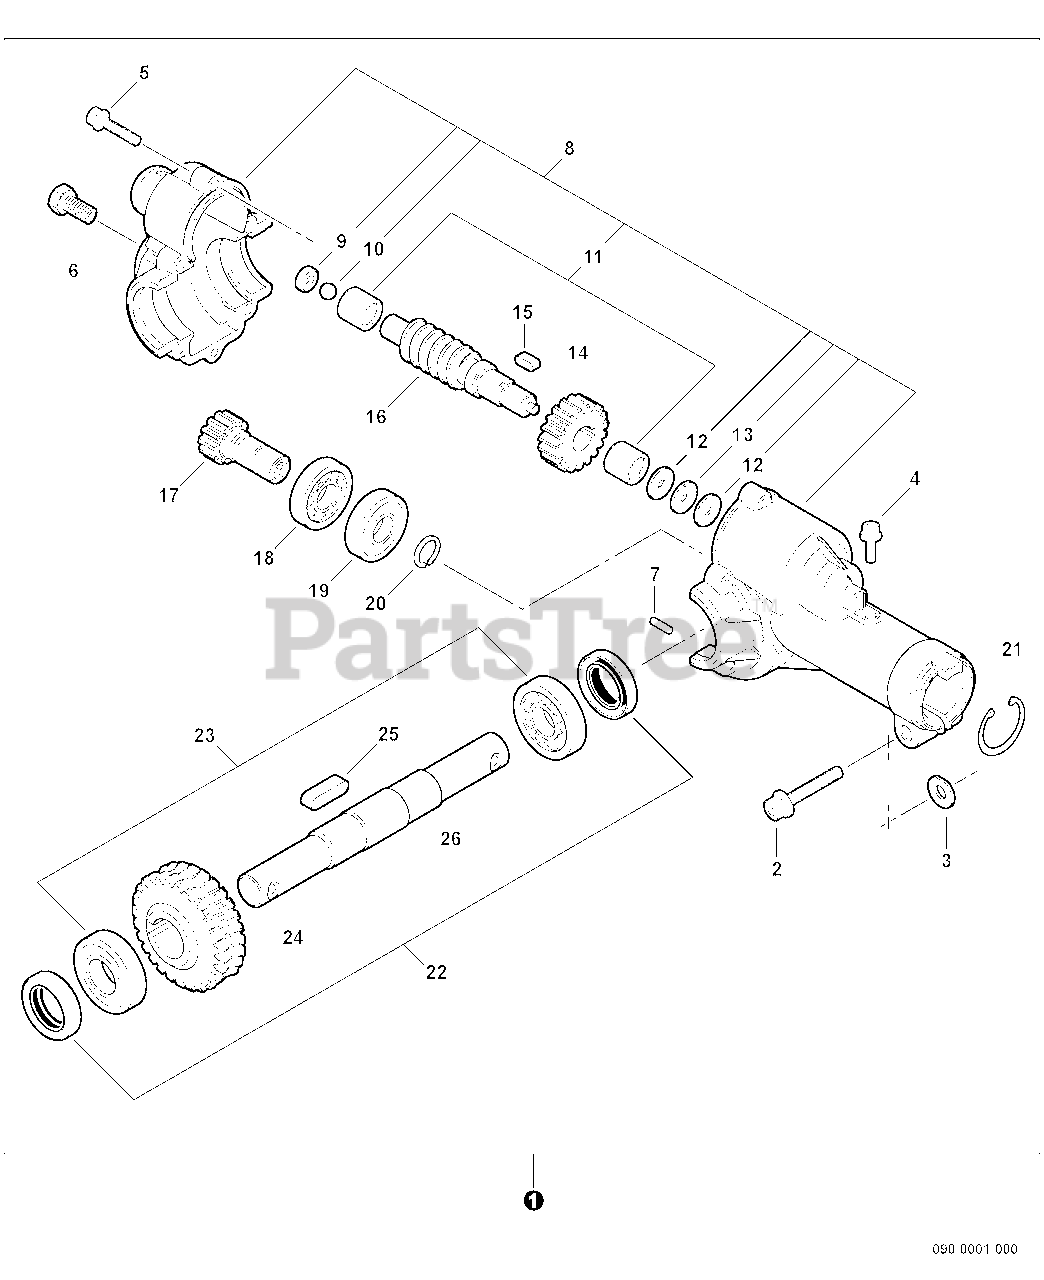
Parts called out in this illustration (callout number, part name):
1	GEAR CASE ASSY
2	SCREW - 6X30
4	SCREW - 5X12
5	SCREW - 5X20
6	BOLT - 8X10
7	PIN - LOCATING
8	GEAR CASE ASSY
9	BUSHING
11	BEARING, NEEDLE
13	BEARING, THRUST
14	GEAR - SPUR
16	GEAR - WORM
17	GEAR - SPUR
18	BEARING, BALL - 6901
19	BEARING, BALL - 6901
20	RING, RETAINING - 12
21	RING, RETAINING - 24
22	SEAL, OIL - 17
23	BEARING, BALL - 6003
24	WHEEL, WORM
26	GEAR - SHAFT
